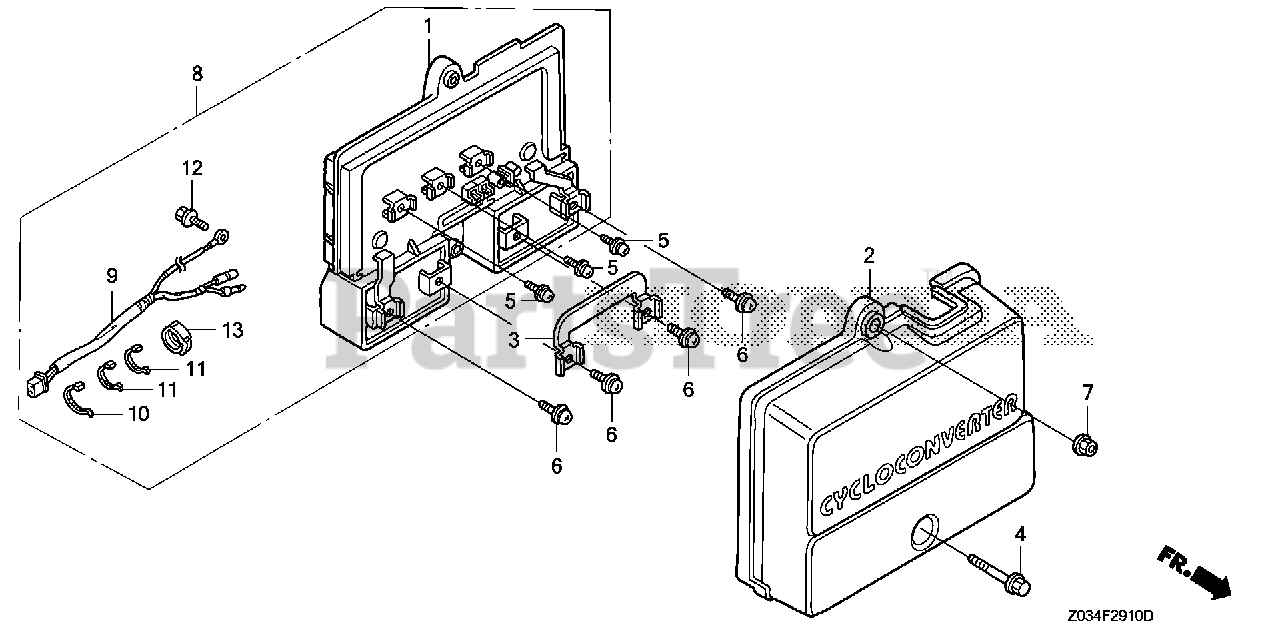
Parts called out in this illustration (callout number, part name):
1	CYCLOCONVERTER UNIT
2	COVER, CYCLOCONVERTER UNIT
3	BAR, CONNECTING
4	BOLT, FLANGE (6X28) (CT200)
5	SCREW-WASHER (4X8)
6	SCREW-WASHER (5X8)
7	NUT, FLANGE (6MM)
